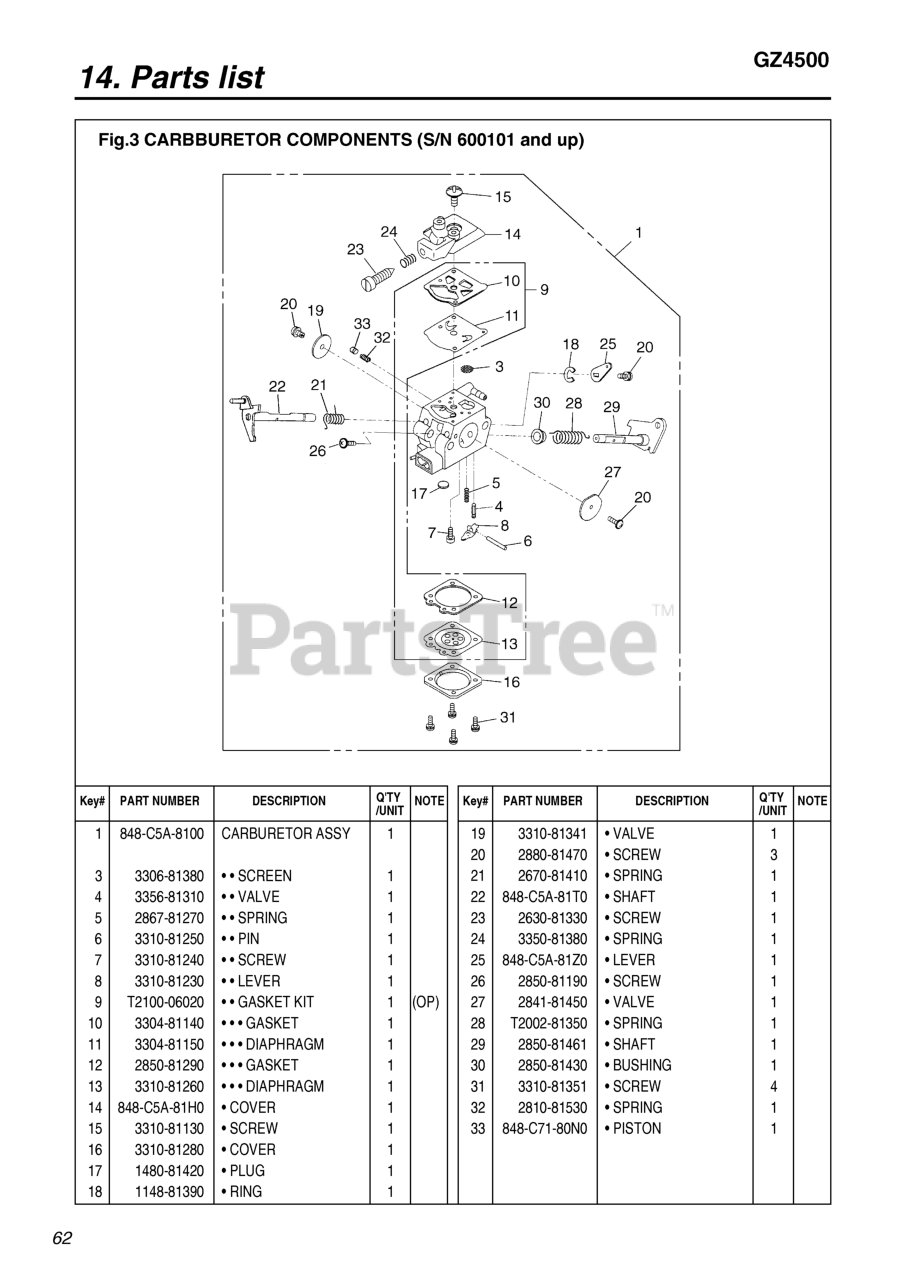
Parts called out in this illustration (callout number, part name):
1	CARBURETOR ASSY
4	VALVE, INLET
5	SPRING (RPLS 2841-81270)
6	PIN, METERING LEVER
8	LEVER
9	KIT, GASKET (G3800AVS)
10	GASKET, PUMP
11	KIT ONLY
13	DIAPHRAGM (USE 4810-81260)
14	COVER
17	PLUG, WELSH
20	SCREW (RPLS 3310-81360)
21	SPRING, RETURN
22	SHAFT
24	SPRING, IDLE
25	LEVER
29	SHAFT, CHOKE
31	SCREW ASSEMBLY
33	PISTON
